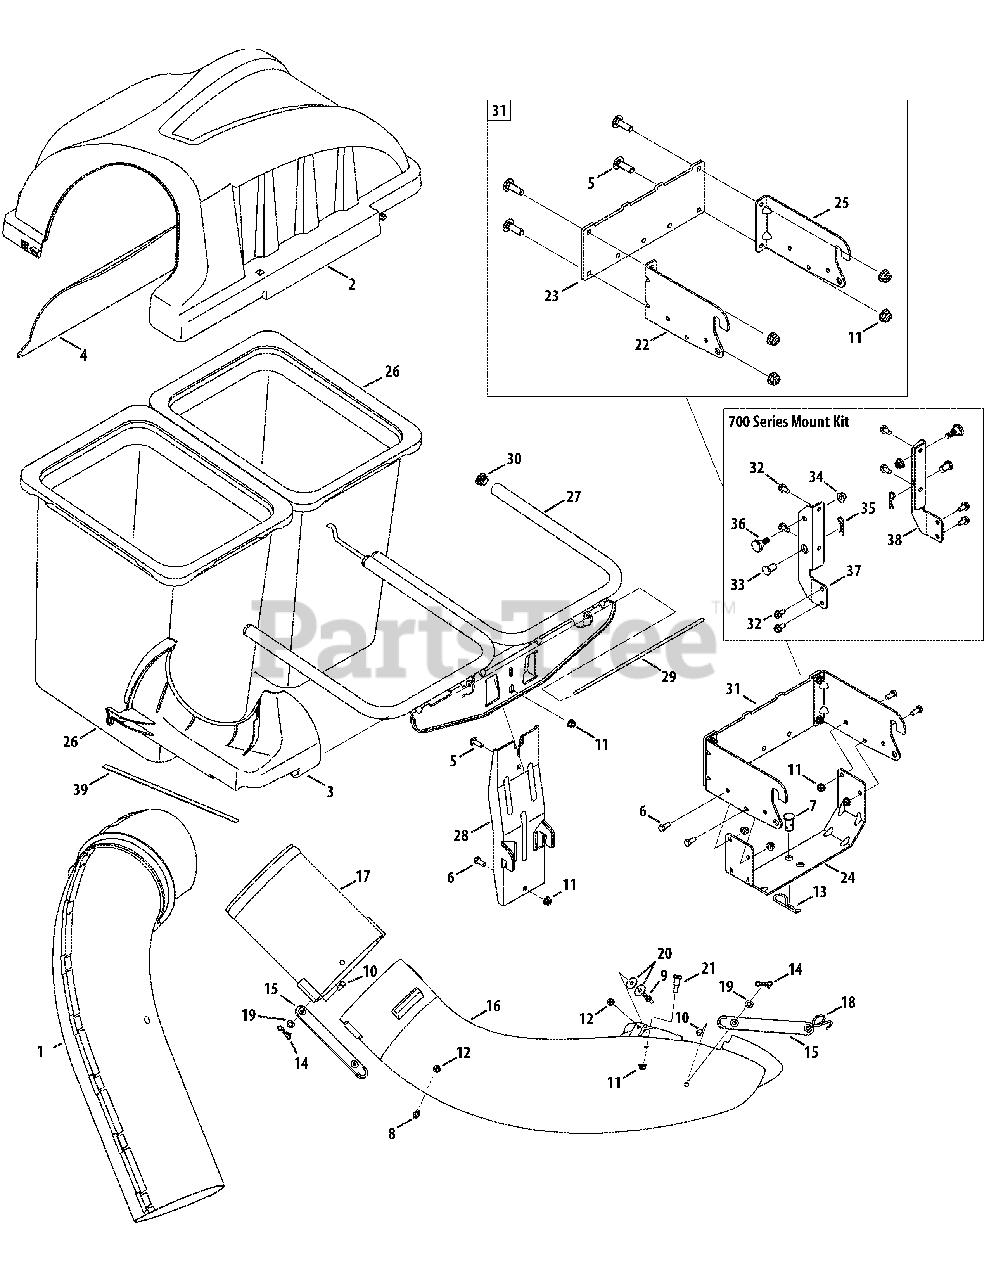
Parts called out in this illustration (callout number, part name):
1	Upper Chute Assembly
2	Double Bagger Cover Assembly
3	Upper Chute Support
4	Bagger Cover Screen
5	Carriage Screw, 5/16-18 x 1.00"
6	Hex Head Screw, 5/16-18 x .75"
7	Clevis Pin, .62" Dia.
8	Grass-catcher Pin, 1/4-20
9	Attachment Pin, 1/4 x 0.66 Lg.
10	Clevis Pin, 5/16 x .75 Lg.
11	Flange Lock Nut, 5/16-18
12	Flange Lock Nut, 1/4-20
13	Internal Cotter Pin, .148 x 3.00
14	Bow-Tie Cotter Pin, 72
15	Chute Strap, 6.00 Lg.
16	Bagger Discharge Chute, Elbow
17	Bagger Chute Adapter, 7 In.
18	Torsion Spring Hook
19	Flat Washer, .344 x .62 x .033
20	Flat Washer, .265 x .938 x .120
21	Shoulder Screw, .437 x .54
22	Mounting Bracket, RH
23	Universal Mounting Bracket
24	Universal Bracket Support
25	Mounting Bracket, LH
26	Grass-bag Assembly
27	Double Bag Support Assembly
28	Vertical Support Bracket
29	Cover Hinge Pin
31	Mounting Bracket Kit (Incl. ref. 22, 23, 25)
32	Tap Screw, 5/16-18 x .750
33	Clevis Pin, .50 x .78 Lg.
34	Flange Lock Nut, 3/8-16
35	Click Pin, .092 x 1.64 Lg.
36	Shoulder Screw, .625 x .412
37	Mounting Bracket, RH
38	Mounting Bracket, LH
39	Self-Adhesive Foam Strip
